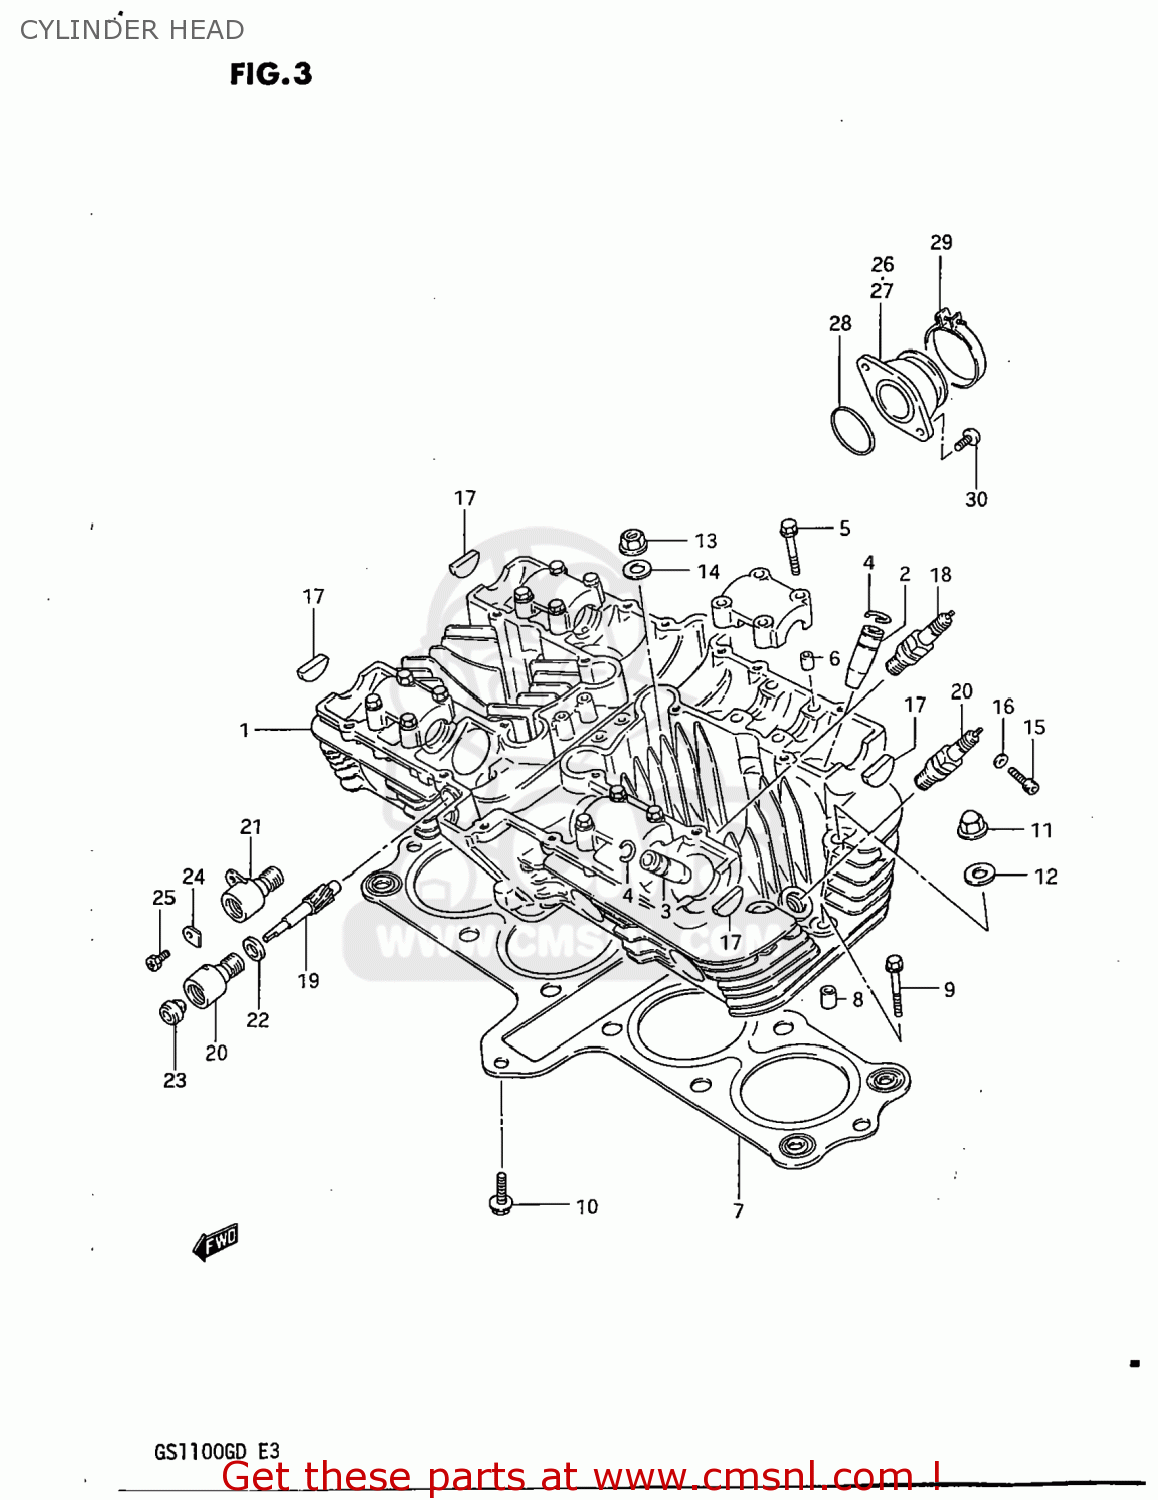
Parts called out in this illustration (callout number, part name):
1	HEAD ASSEMBLY,CYLINDER
2	GUIDE,INTAKE VALVE
3	GUIDE,EXHAUST VALVE
4	RING,SNAP
5	BOLT(6X39)
6	PIN(6.2X8X11)
7	GASKET,CYLINDER HEAD (NAS)
8	PIN
9	BOLT,UNDER
10	BOLT
11	NUT
12	GASKET(10.5X22X2) (NAS)
13	NUT
14	WASHER(10.5X22X2.3)
15	BOLT
16	GASKET(5.3X9.3X1.2) (NAS)
17	PLUG
18	PLUG,SPARK
19	GEAR,TACHOMETER DRIVEN
20	SLEEVE,TACHOMETER DRIVE
21	SLEEVE,TACHOMETER DRIVE GEAR
22	SEAL,TACHOMETER DRIVEN
23	SEAL,OIL(5X12X8)
24	PLATE,TACH DRIVE GEAR SLEEVE
25	SCREW(5X12)
26	PIPE,INTAKE,R
27	PIPE,INTAKE,L
28	O-RING (D:2.4 ID:39.7)
29	CLAMP
30	SCREW
